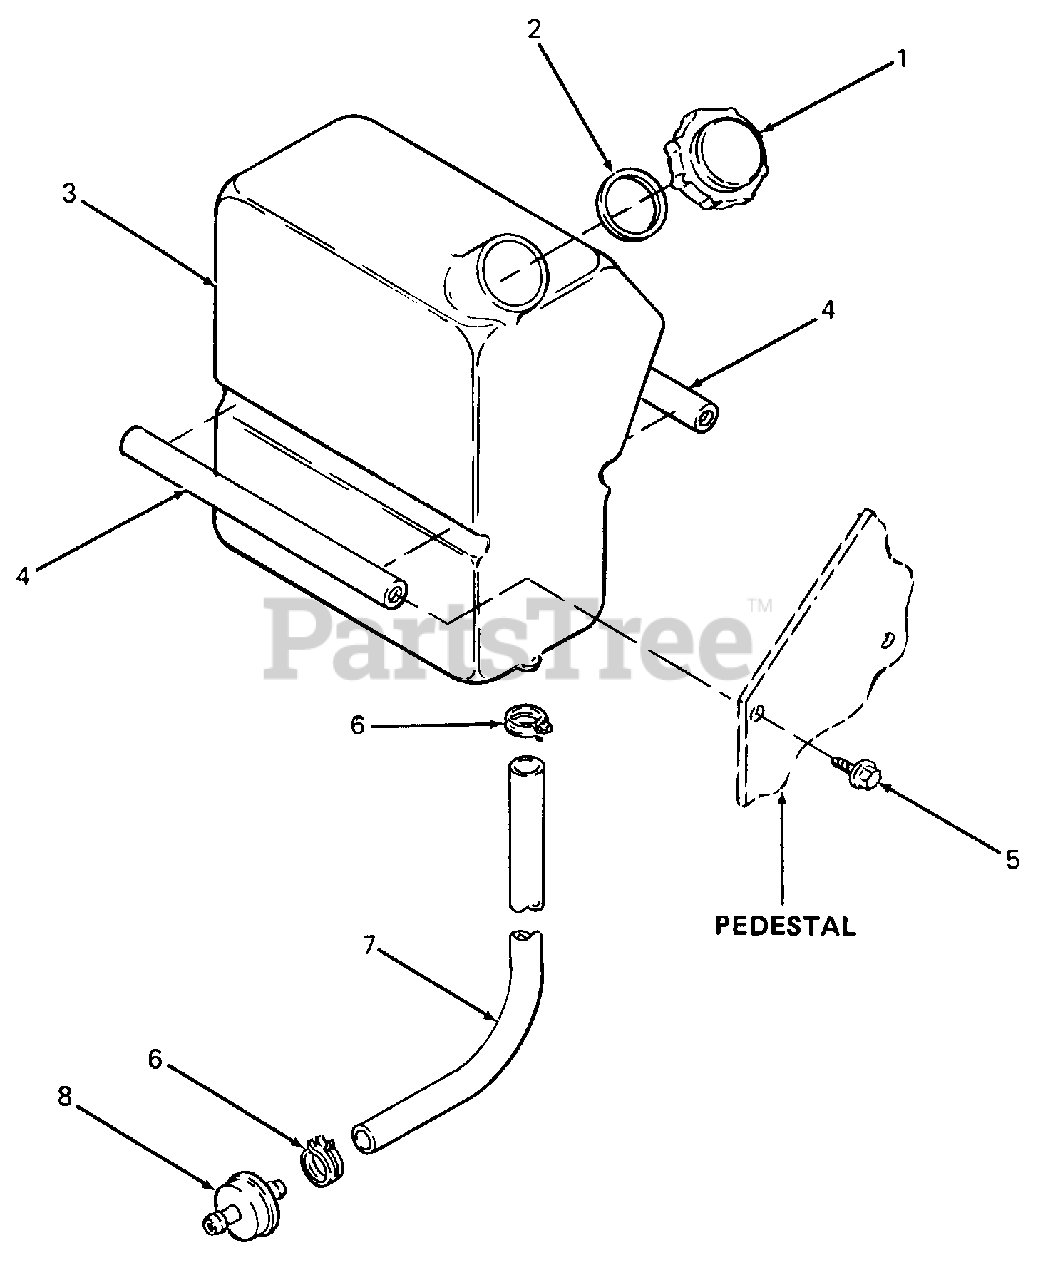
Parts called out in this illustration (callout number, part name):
1	Cap, Fuel
2	Gasket, Fuel Tank Cap
3	Tank, Fuel
4	Tube, 11.27 Lg
5	Screw, Hex Wash Hd B Tapp, 5/16-18 X .50 Lg
6	Clamp, Hose
7	Line, Fuel, 10 in. Lg
8	Filter, Fuel
